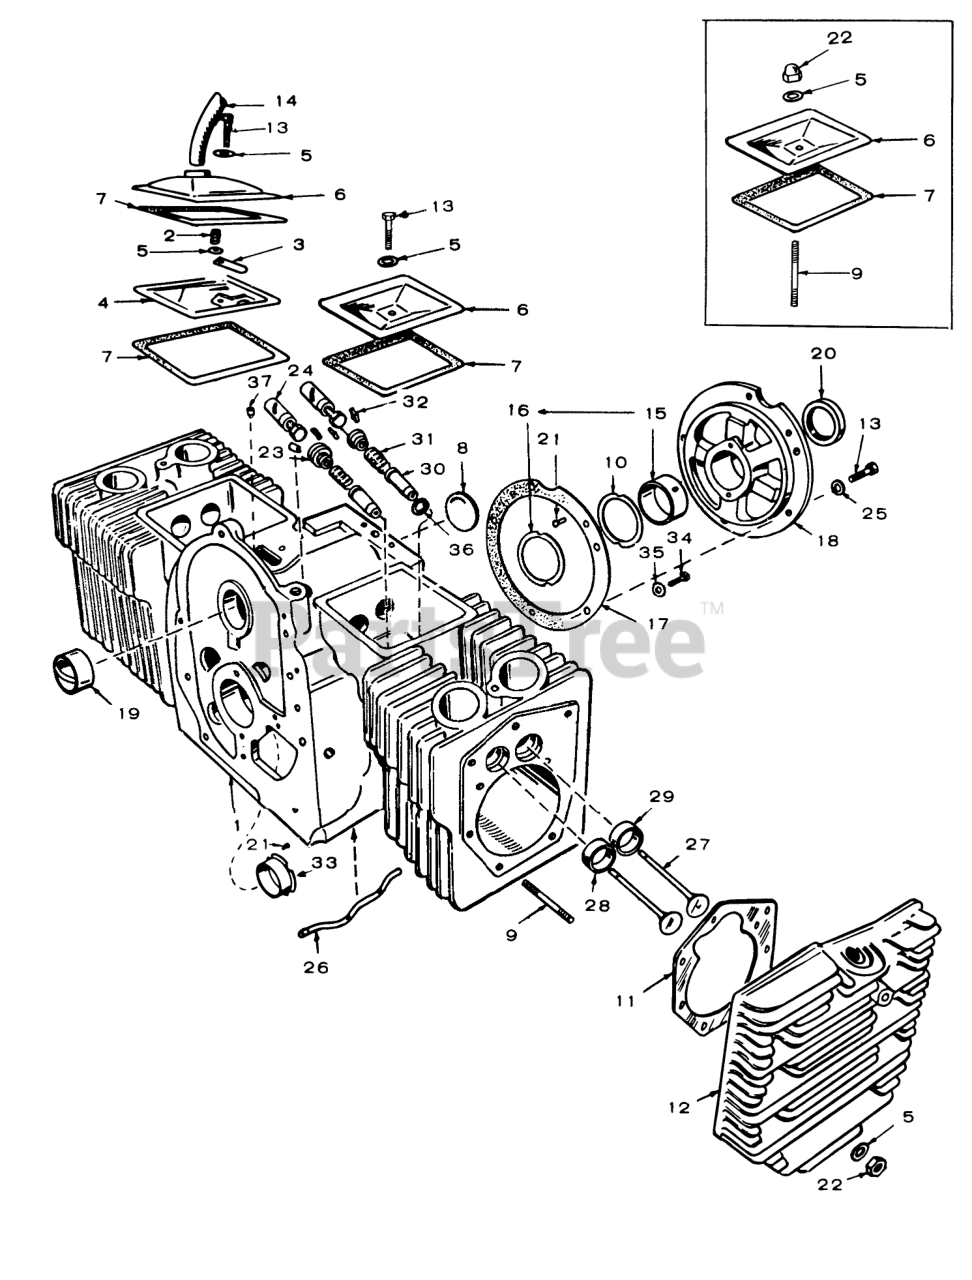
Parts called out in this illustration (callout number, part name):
5	WASHER, FLAT
5	Breather Valve (1/4"-Steel)
5	Washer, Cyl Head Screws 5/16 in
6	COVER, VALVE COMPARTMENT
7	Valve Cover Gasket
9	Stud
9	STUD-CYL HEAD
12	HEAD, CYLINDER
13	SCREW, HEX CAP
13	*Cap Screw-Bearing Plate
13	Cap Screw-Valve Cover
15	BEARING, CRANKSHAFT-REAR
15	Standard
15	.002" Undersize
15	.010" Undersize
15	.020" Undersize
15	.030" Undersize
21	Pin-Main Bearing Stop
22	Nut
22	Cylinder Head-Hex (5/16-24)
24	Tappet, Valve
24	.001" Oversize
24	.002" Oversize
24	.005" Oversize
25	*Lockwasher-Rear Bearing Plate
27	Valve
28	Insert, Valve Seat-Exhaust
28	.002" Oversize
28	.005" Oversize
28	55095 ADD.REPLAC.PA
28	.025" Oversize
29	INSERT, VALVE SEAT-INTAKE
29	.002" Oversize
29	.005" Oversize
29	.010" Oversize
29	.025" Oversize
30	Valve Guide
33	BEARING, CRANKSHAFT-FRONT
33	.002" Undersize
33	.010" Undersize
33	.020" Undersize
33	.030" Undersize
34	Cap Screw-Cylinder Block
